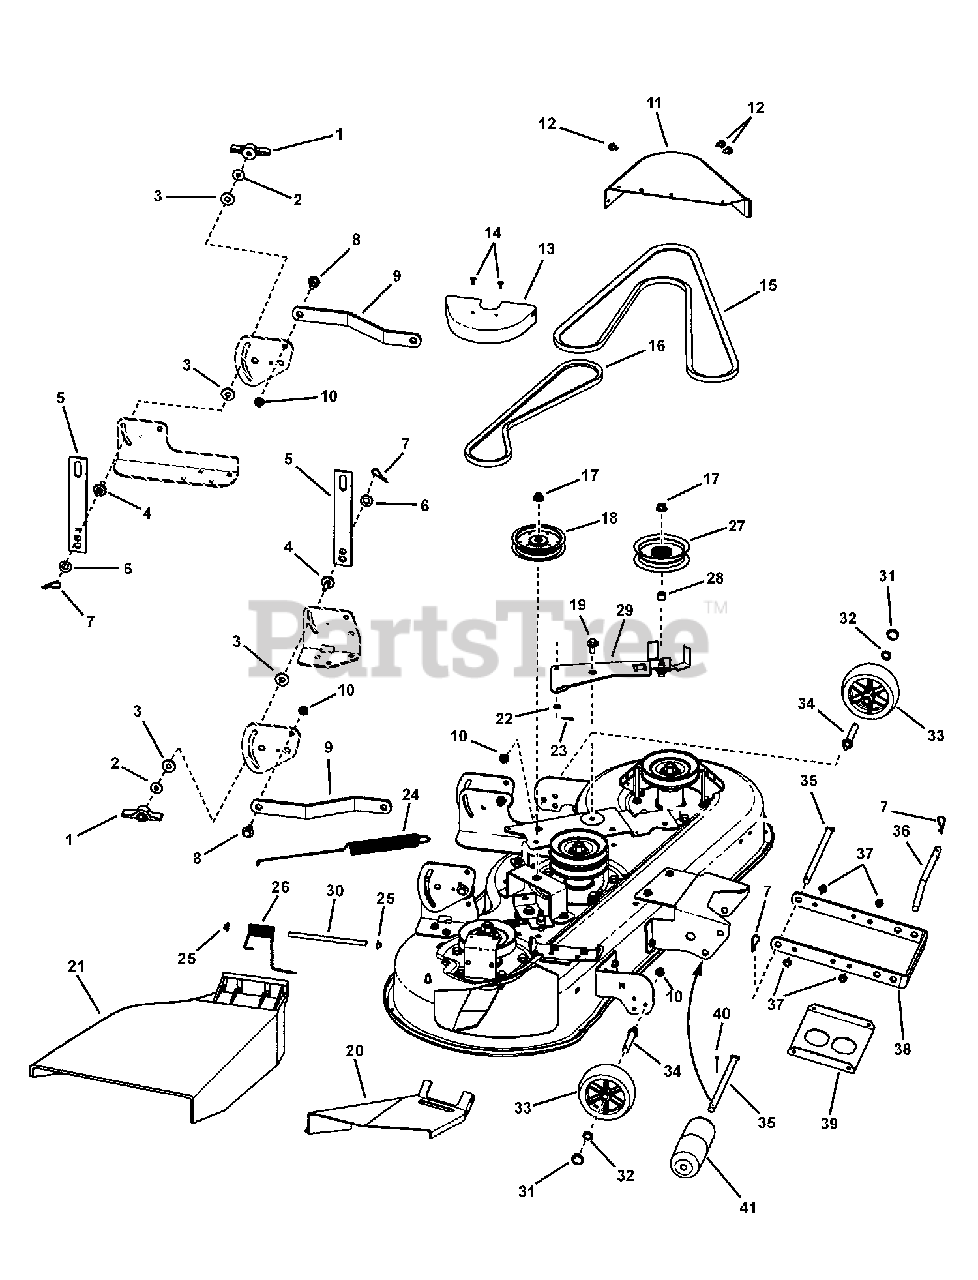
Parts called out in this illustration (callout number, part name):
1	KNOB (5/16-18 thread)
2	WASHER, Flat, 1.0 x .328 x 16 GA
3	FRICTION PAD
4	PIN - Hanger 3/8-16 x 1-1/4"
5	LINK, Lift
6	WASHER, Flat, 1.0OD x 0.550"
7	HAIR PIN, .092 Dia.
8	SHOULDER BOLT, 3/8-16 x .600 OD x .95 L
9	BRACKET, Rear Suspension
10	NUT, 3/8-16 Hex Flange Lock, NC
11	COVER, Left Pulley
12	SCREW, 5/16-18 x 1/2" Hex Washer Head
13	COVER, Right Pulley
14	SCREW, #10-24 Thread Forming (.340 Min Threads)
15	V-BELT, (83.10" HA) 46 Mower No Logo
16	BELT, Secondary (47.10" HA) 46 Mower
17	NUT, 3/8-16 Hex Flange, Zinc Plated
18	PULLEY, Idler, (4.0 OD, straight edges) R.H. side
19	BOLT, 3/8-16 Shoulder
20	DEFLECTOR, Inside
21	DEFLECTOR, Chute
22	WASHER, .34 x .62 x 16 GA Flat
23	PIN, .090 x 3/4 Cotter
24	SPRING, Extension
25	CAP, Push On (for .375 dia. Stud)
26	SPRING - Torsion
27	PULLEY, Idler, (4.0 OD, flared edges) L.H. side
28	SPACER, 1/2 To 17mm
29	ASSY - Idler Arm, 46 Deck
30	ROD, Deflector
31	CLIP - Hair Pin
32	WASHER, Flat, .81 x .550 x 16 Ga
33	WHEEL, Gage
34	BOLT, Axle, 3/8-16 x 3.0
35	ROD, Deck Suspension
36	ROD, Hanger
37	CAPSCREW, 5/16-18 Hex Washer Face
38	BRACKET, Front Suspension
39	STIFFENER
40	COTTER PIN, 1/8 x 1-1/4"
41	ROLLER
